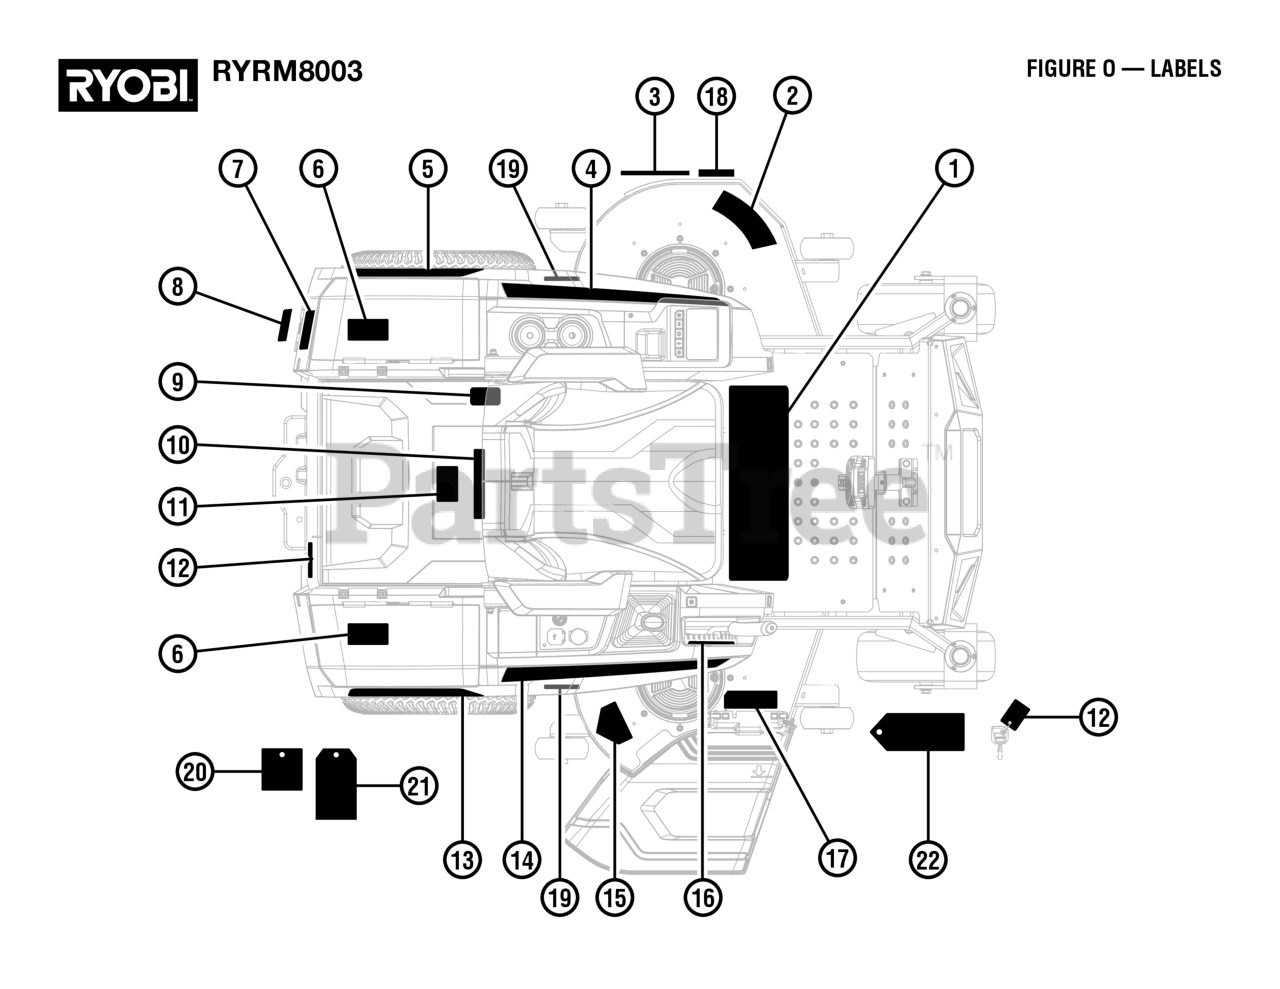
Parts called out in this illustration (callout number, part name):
1	Danger/Warning/Joystick Control/Brake Label (Eng)
1	Danger/Warning/Joystick Control/Brake Label (Sp)
2	Deck Danger Label, English
2	Deck Danger Label, Spanish
3	Cutting Width Deck Part A Label
4	80V HP Brushless Hero Label
5	Sub Brand Logo Hero Label
6	40V Battery Connection Instrucion Card
8	Charging Port Label (Eng)
8	Charging Port Label (Sp)
9	Data Label
10	FCC Label
11	80V Battery Connection Instrucion Card
12	Key Chain Tag (Eng)
12	Key Chain Tag (Sp)
13	Sub Brand Logo Non-Hero Label
14	80V HP Brushless Non-Hero Label
15	No Hands CPSC Danger Label, English
15	No Hands CPSC Danger Label, Spanish
16	Deck Height Adjustment Label
17	Discharge Chute Icons
18	Cutting Width Deck Part B Label
19	Pinch Point Icon Label
20	Prop 65 Hangtag
21	Seat Assembly Tag
22	Joystick Hangtag
